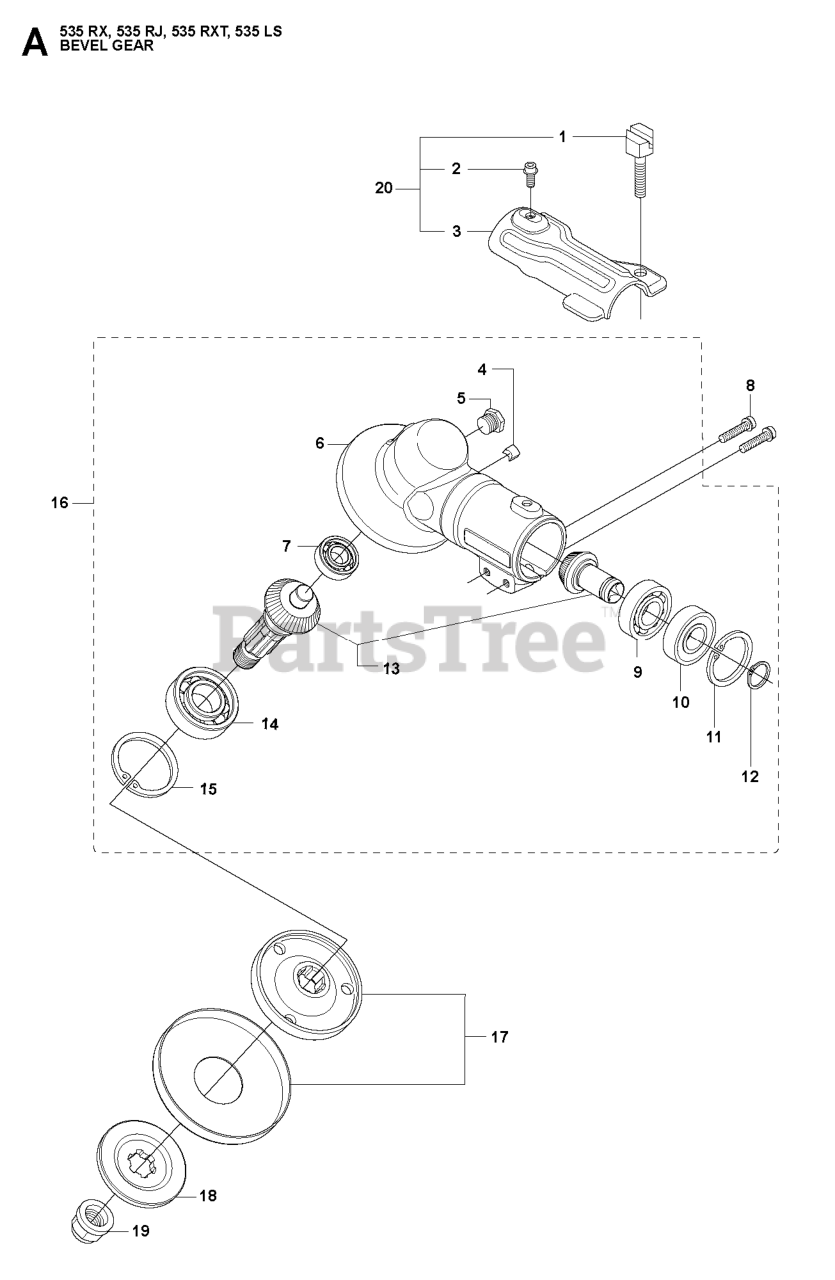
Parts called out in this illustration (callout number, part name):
2	SCREW
3	RP HOLDER
7	BALL BEARING 24X9X1/609ZR
9	BALL BEARING
10	BALL BEARING
11	RETAINING RING SGH 28
12	SEEGER CLIP
13	SPARE PARTS KIT
14	BALL BEARING
15	RETAINING RING
16	%GEAR CASE ASSY
16	GEAR COMPLETE
17	CARRIER
18	RP FLANGE
20	CLAMP
